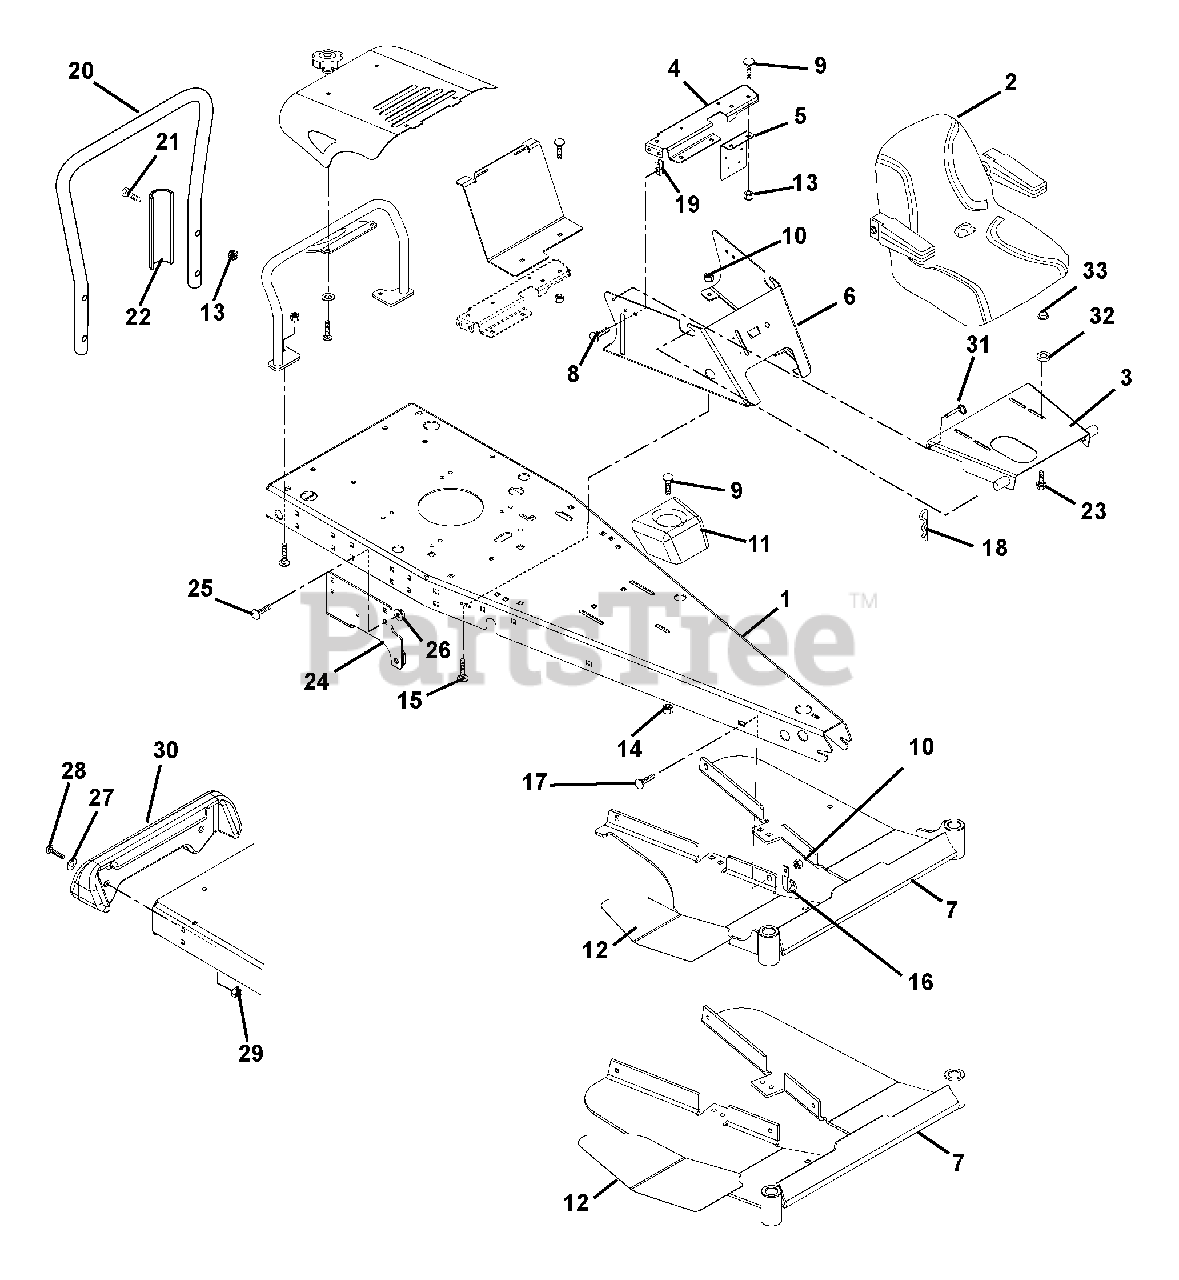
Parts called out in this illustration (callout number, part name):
2	Seat, TS2500 Michigan with Arms
3	Weldment, Seat Plate
4	Reforcement, Seat Support
5	Panel, Solenoid Mounting
6	Seat Support
7	Weldment, Footrest (066)
7	Weldment, Footrest (068)
8	Bolt-Serrated Hex Flange Washer Head .25-20 x .75
9	Bolt, Round Head Square Neck .31-18 x .75 Grade 5
10	Nut, Locking Top Flange .38-16
11	Cupholder
12	Grip, Footrest Left Hand (066)
12	Grip, Footrest Left Hand (068)
12	Grip, Footrest Right Hand (066)
12	Grip, Footrest Right Hand (068)
13	Nut-Locking-Top-Flange .31-18
14	Nut-Spin Lock-Flange .312-18
15	Bolt-Round Head Square Neck .38-16 x .75 Grade 5
16	J-Clamp
17	Bolt-Round Head Square Neck .38-16 x 1.00 Grade 5
18	Pin-Hair-External .12 x .31 x 2.37
19	Nut-Retainer .25-20 x .56
20	Tube (066, 068)
21	Bolt, Hex .31-18 x 1.50 Grade 5 (066, 068)
22	Brace (066, 068)
23	Bolt-Serrated Hex Flange Washer Head .31-18 x 1
24	Bracket, Transmission - Right Hand
24	Bracket, Transmission - Left Hand
25	Bolt, Round Head Square Neck .38-16 x .75 Grade 5
26	Nut, Locking Top Flange .38-16
27	Washer-Flat-Steel .438 x 1.00 x .083
28	Bolt-Hex .38-16 x 1.75 Grade 5
29	Nut-Locking-Top-Flange .38-16
30	Weight
31	Pin, Detent with Ring .25 x 1.00
33	Nut, Push .312
